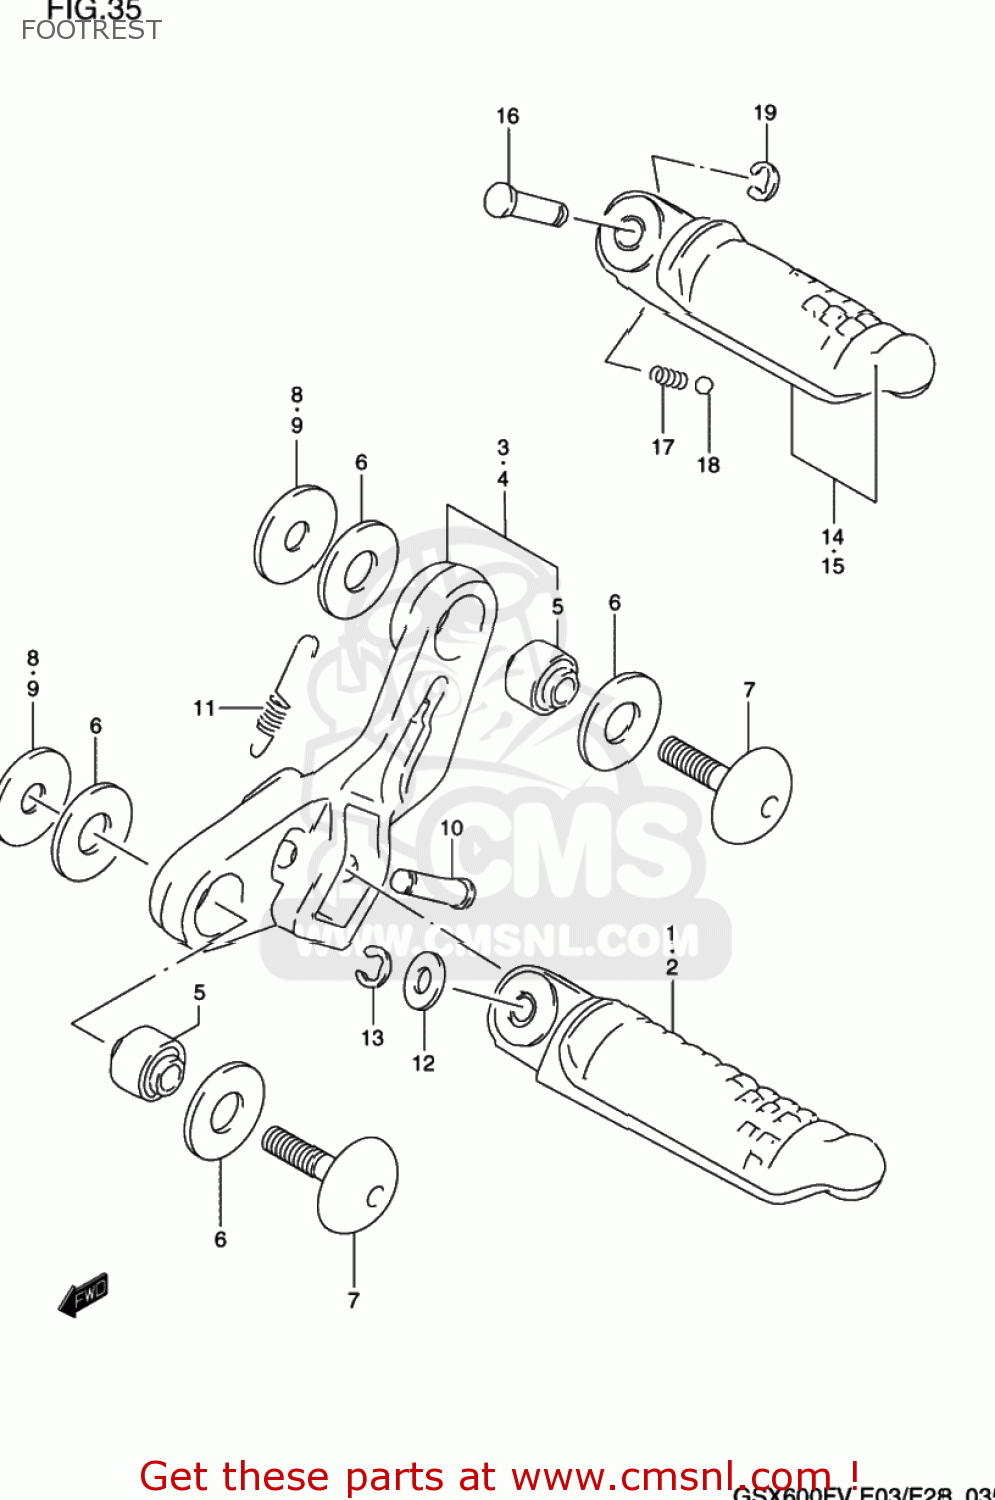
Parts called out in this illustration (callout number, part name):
1	BAR,FRONT FOOTREST,RIGHT
2	BAR,FRONT FOOTREST,LEFT
3	HOLDER,FR FOOTREST,R
4	HOLDER,FR FOOTREST,L
5	BUSH(8.4X20X18)
6	WASHER(12.5X30X2)
7	BOLT(8X33)
8	WASHER (8.5X30X2.3)
9	WASHER(8.5X30X2.3)
10	PIN(8X33.2)
11	SPRING
12	WASHER
13	E.RING
14	BAR,PILLION FOOTREST,RIGHT
15	BAR,PILLION FOOTREST,LEFT
16	PIN
17	SPRING
18	BALL
19	E.RING
